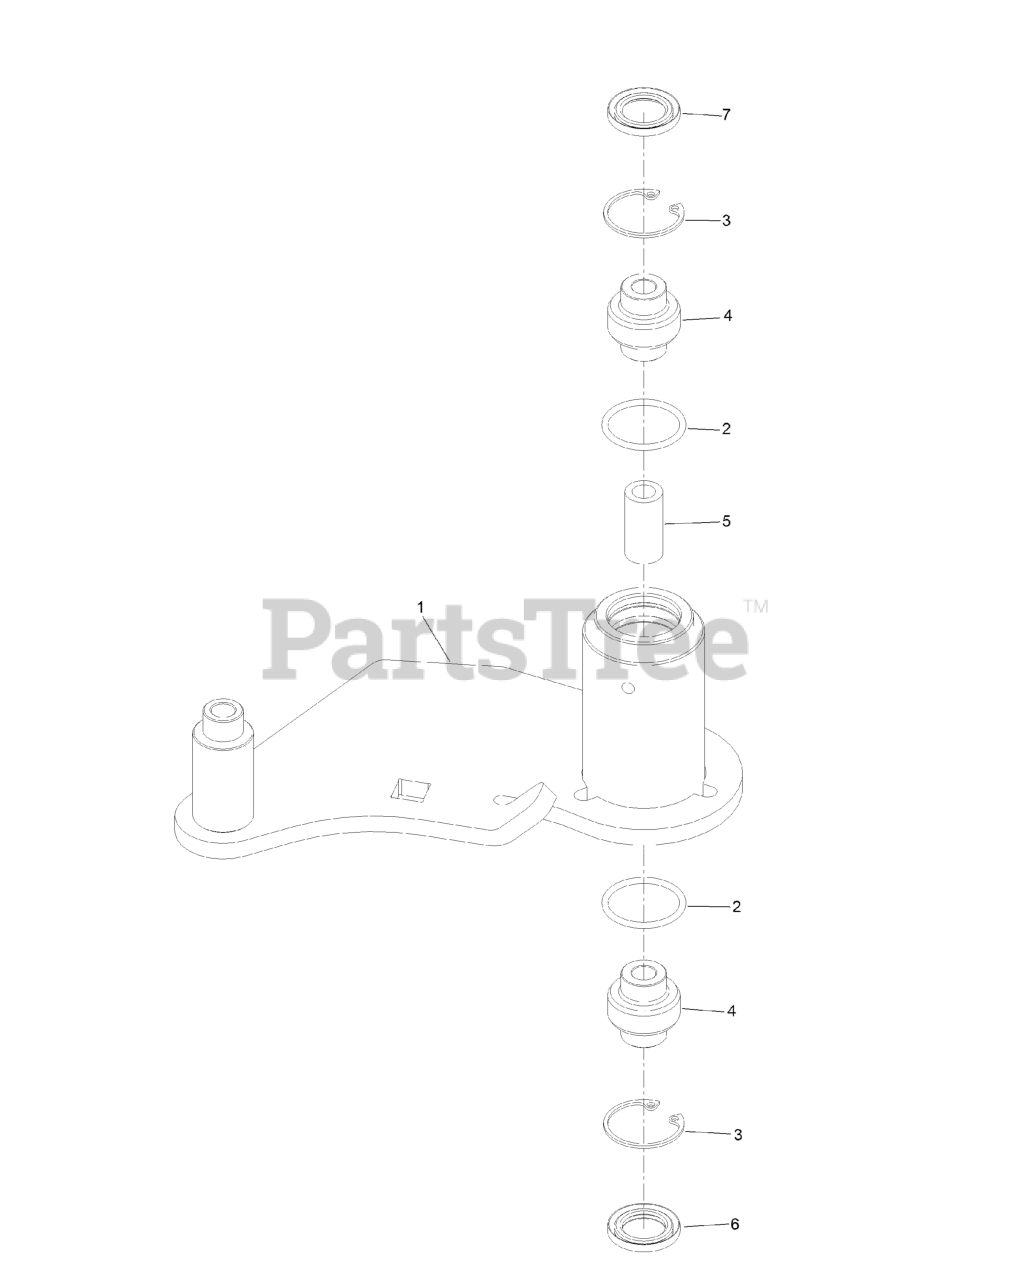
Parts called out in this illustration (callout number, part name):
1	Idler-Deck
3	RING-SNAP
4	BEARING-SPHERICAL
6	SEAL-LIP, DOUBLE
7	SEAL-LIP, SINGLE
